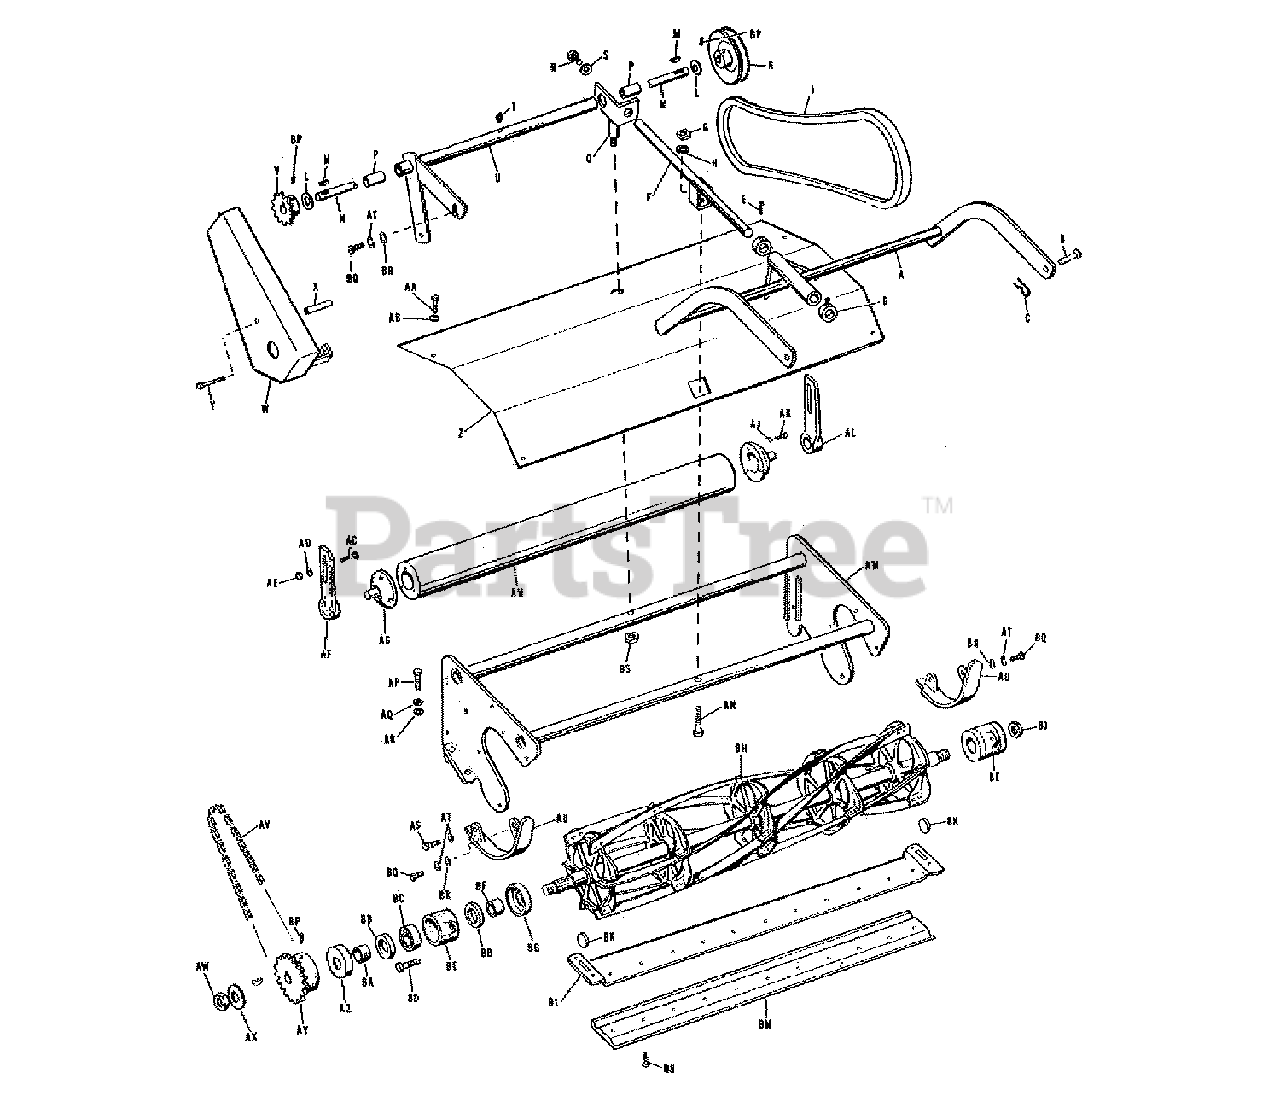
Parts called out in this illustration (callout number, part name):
A	HITCH ASSEMBLY
C	CLIP, Spring
D	COLLAR, Set
E	SET SCREW, Square Head, 5/16-18 x 1/2"
F	PIVOT ASSEMBLY
G	SQUARE NUT, 3/8" NC
H	LOCKWASHER, 3/8"
J	V" BELT, 28" Long`
M	WOODRUFF KEY, 3/16 x 3/4, No.9
N	SHAFT, Pulley
Q	SUPPORT ASSEMBLY
S	LOCKWASHER, 3/8"
T	ZERK FITTING
U	JACKSHAFT HOUSING & BAIRING ASSEMBLY
V	SPROCKET
W	CHAIN GUARD ASSEMBLY
X	SPACER
Y	CAPSCREW, 3/8-16 x 3-1/4"
Z	SHIELD, Grass
AA	CAPSCREW, 3/4-28 x 1/2"
AB	LOCKWASHER, 1/4"
AC	CARRIAGE BOLT, 3/8-16 x 1-1/4"
AD	LOCKWASHER, 3/8"
AE	NUT, Full Hex, 3/8-16
AF	ROLLER BRACKET ASSEMBLY, R.
AG	SHAFT, Ring
AH	ROLLER ASSEMBLY
AJ	LOCKWASHER
AK	SCREW, Socket Head
AL	ROLLER BRACKET ASSEMBLY, L.
AM	FRAME ASSEMBLY
AN	CAPSCREW, 3/8-16 x 2"
AP	CAPSCREW, 7/16-20 x 1 3/4"
AQ	WASHER, Upper
AR	WASHER, Lower
AT	LOCKWASHER, 5/16"
AU	GUARD, Reel
AV	CHAIN, Drive, w/Link
AX	WASHER, Cut
AY	SPROCKET
AZ	SLINGER, Outer
BA	SPACER, Outer
BB	SEAL, Grease
BC	BEARING, Ball
BD	BOLT, Bearing Housing
BE	HOUSING, Bearing
BF	SPACER, Innter
BG	SLINGER, Inner
BH	REEL ASSEMBLY, 6 Blade
BK	DISC, Pivot
BL	BED BAR ASSEMBLY
BM	KNIFE, Bed
BN	SCREW, Knife
BP	SET SCREW, Socket Head, 5/16-18 x 5/16
BQ	CAPSCREW, 5/16-24 x 3/8"
BR	WASHER, 1/4 S.A.E.
